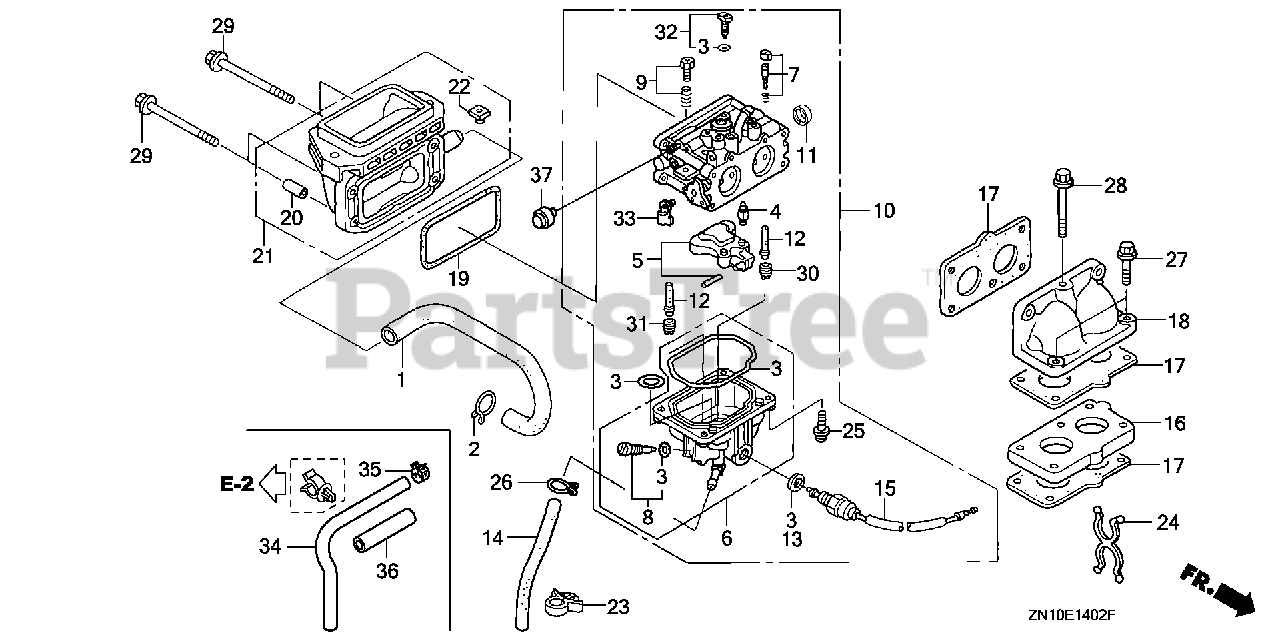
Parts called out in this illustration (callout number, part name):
1	TUBE, BREATHER
2	CLIP, BREATHER TUBE
3	GASKET SET
4	VALVE SET, FLOAT
6	CHAMBER SET, FLOAT
7	SCREW SET, PILOT
8	SCREW SET, DRAIN
9	SCREW SET, THROTTLE
10	CARBURETOR ASSY. (BK01G B)
11	CAP, CHOKE DUST
12	NOZZLE, MAIN
13	WASHER, PLAIN
14	TUBE, DRAIN
15	VALVE ASSY., SOLENOID (KEIHIN)
16	INSULATOR, CARBURETOR
17	GASKET, CARBURETOR
18	ELBOW, MANIFOLD
19	GASKET, AIR CLEANER
20	COLLAR A, AIR CLEANER
21	ELBOW, AIR CLEANER
22	NUT, INSERT (6MM)
23	CLIP B, CABLE (9MM BLACK)
24	CLIP, PURSE LOCK
25	SCREW, PAN (4X12)
26	CLIP, TUBE (B8)
27	BOLT, FLANGE (6X30)
28	BOLT, FLANGE (6X65)
29	BOLT, FLANGE (6X90)
30	JET, MAIN (#88)
30	JET, MAIN (#92)
30	JET, MAIN (#98)
31	JET, MAIN (#92) (CARBURETOR NO.)
31	JET, MAIN (#98) (CARBURETOR NO.)
31	JET, MAIN (#102)
32	JET SET, PILOT (#38) (CARBURETOR NO.)
33	ARM, THROTTLE LINKAGE
